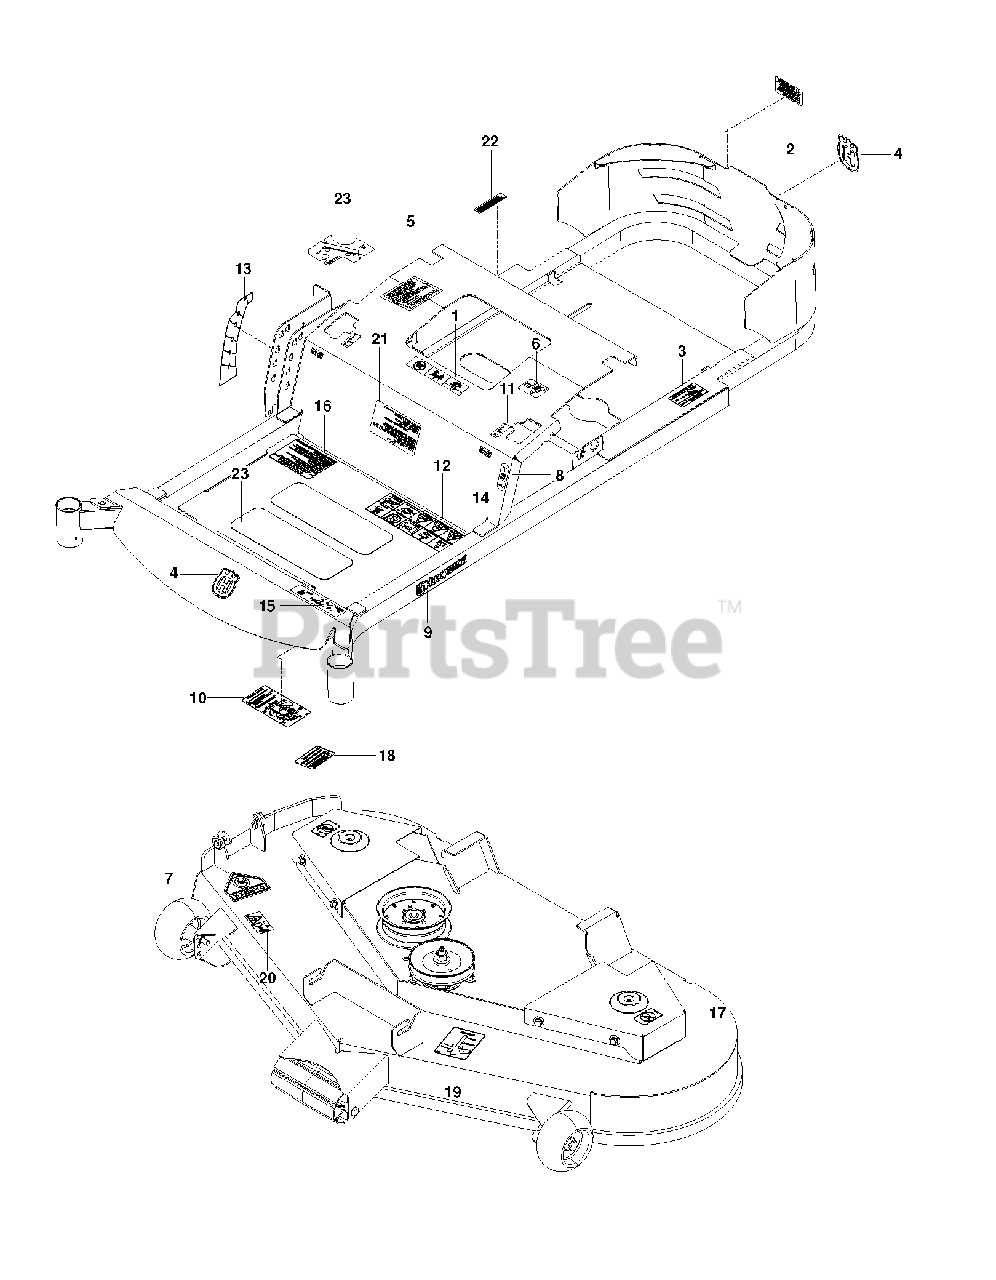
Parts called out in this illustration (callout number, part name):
1	EURO DECAL-BATTERY WARNIN6
2	DECAL, PROP. 65
3	DECAL, DO NOT TOW
4	DECAL.AUGER.HUSQ.CROWN.SNOW
5	DECAL, CUSTOMER RESPNSIBILITY
6	DECAL, EXITING MOWER
7	DECAL, CPSC
8	DECAL, PARK BRAKE
9	RP.DECAL.BADGE.170MM.TEXTLOGO
10	DECAL, SERVICE
11	DECAL, MOTION CONTROL
12	DECAL, SAFETY WARNING
13	DECAL, DECK HEIGHT, HUSQ
14	DECAL, F.S.T.
15	DECAL, EZ4824
16	DECAL, WARNING
17	DECAL, NO STEP
18	DECAL, CAUTION
19	DECAL, BELT ROUTING
20	DECAL, EURO SEVERING
21	DECAL, START
22	DECAL, WARNING SPARK ARRESTOR
23	DECAL, CTRL PANEL, HUSQ
24	ANTI-SKID PAD
